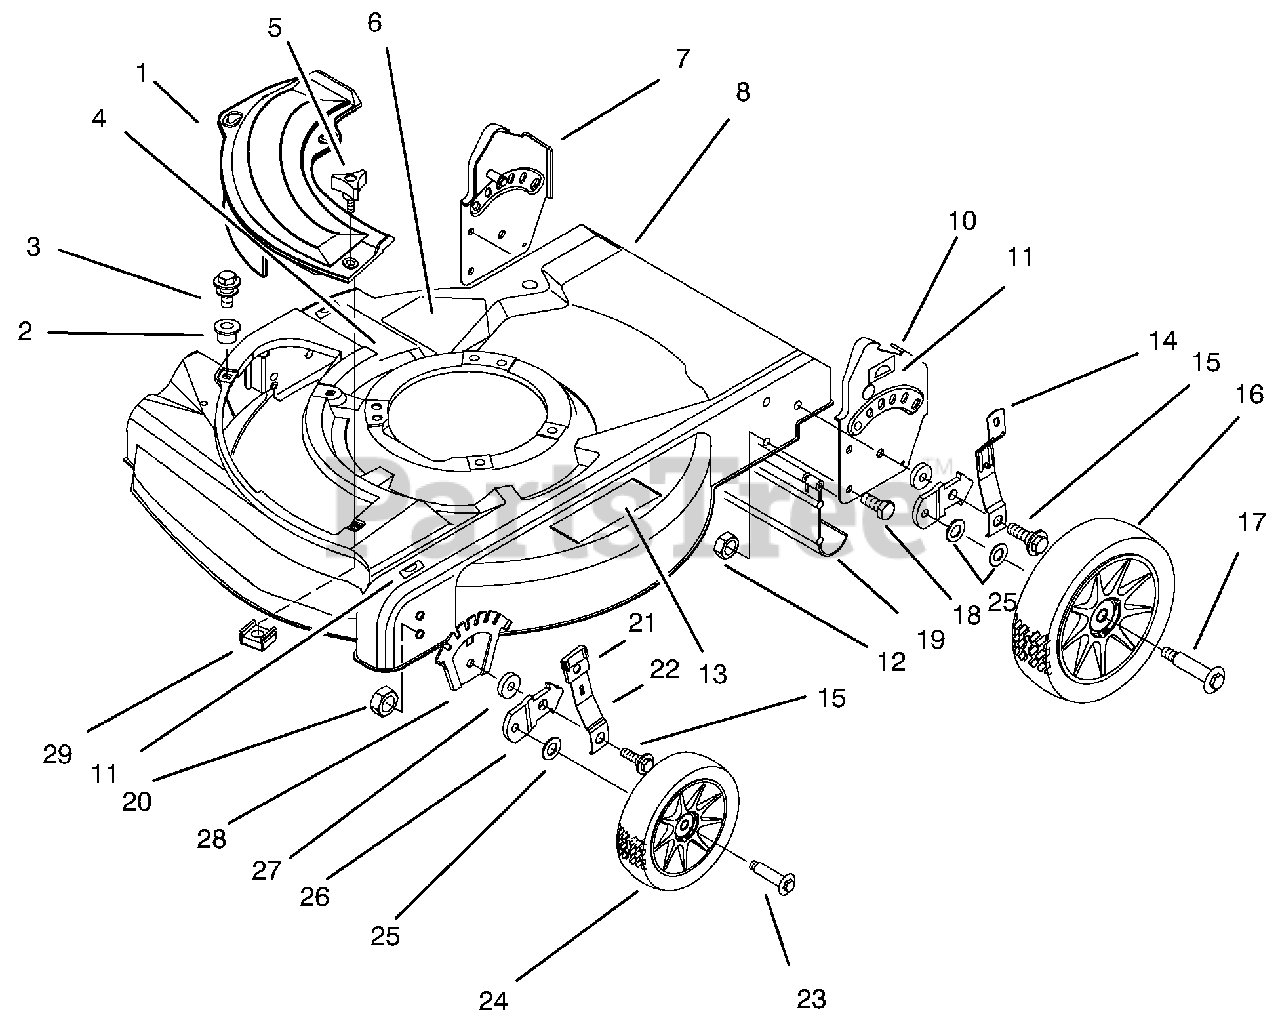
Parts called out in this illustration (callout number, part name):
1	Cover Plate, Mulch
2	Grommet-Plastic
3	Screw-Thread Forming
4	Decal-Danger (English)
5	Knob
6	Decal-Danger (English)
7	Handle Bracket Ass'y-RH
8	Housing & Baffle Ass'y (Incl. ref. #2-6, 9, 11 & 29)
10	Handle Bracket Ass'y-LH
11	Decal-H. O. C. L.H.
13	Decal-Warning
14	Spring Arm Assembly
15	Bolt-Shoulder
16	Wheel Ass'y-8"
17	Bolt-Wheel
18	Screw-Hex Head
19	Shield-Trailing
21	Knob-H. O. C. Lever
22	Spring Arm Assembly, Front
23	Bolt-Wheel
24	Wheel Ass'y-6"
25	Washer-Wheel Bolt
26	Bracket-H. O. C.
28	Plate-H. O. C. Front
29	Nut-Cage
30	Plate-Baffle
